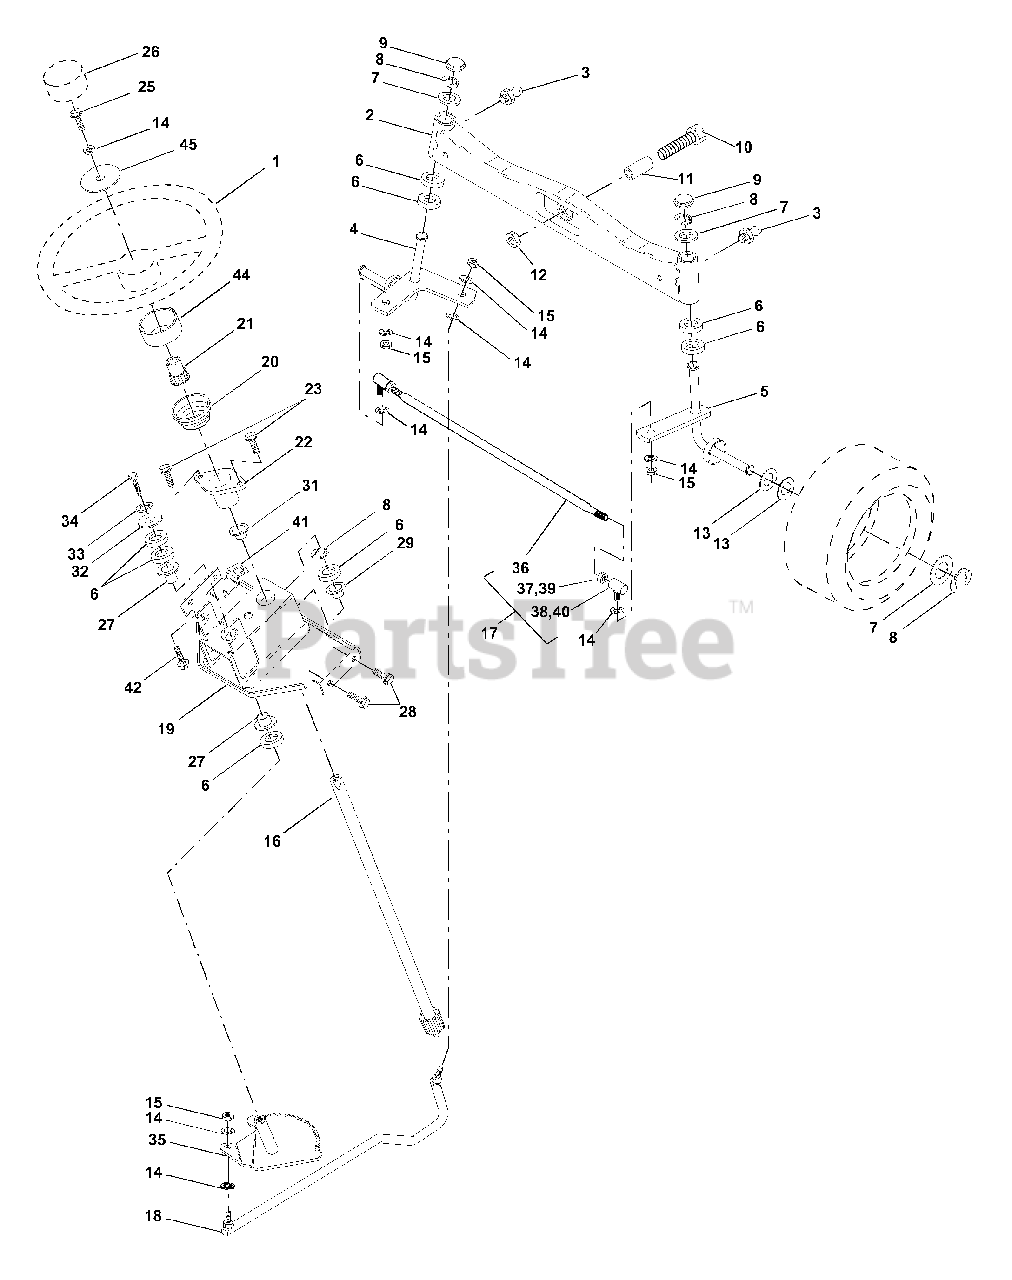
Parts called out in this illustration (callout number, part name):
1	Wheel, Steering
2	Axle, Front
3	Fitting, Grease
4	Spindle Asm, LH
5	Spindle Asm., RH
6	Bearing, Race Thrust Harden
7	Washer 25/32 x 1-5/8 x 16 Ga.
8	Ring, Klip #T5304-75
9	Cap, Spindle
10	Bolt, Fin Hex 5/8-11 x 2-3/4
11	Spacer Brg Axle Front 1.570
12	Nut, Lock Flange 5/8-11 Unc
13	Washer 25/32 x 1-1/4 x 16 Ga.
14	Washer, Lock Hvy Hlcl Spr 3/8
15	Nut Lock Center 3/8-24 Unf
16	Shaft Asm., Steering
17	Rod Asm., Tie Ball J Ball Vgt
18	Draglink, Ball Joint Solid Vgt
19	Support Asm., Steering Vgt
20	Boot Steering
21	Adapter, Wheel Steering
22	Bushing, Strg.
25	Bolt, Fin Hex 3/8-16 x 1 Gr. 5
26	Cap , Wheel Steering
27	Bearing, Col. Strg.
28	Screw 3/8-16 x 3/4
29	Bearing, Flange
31	Bushing, Nyliner Snap
32	Washer 11/32 x 1 x 10 Ga.
33	Washer, Lock Hvy Hlcl Spr 5/16
34	Bolt, Hex Hd 5/16-18 x 3/4
35	Gear, Sector Steering
36	Tie Rod
37	Jam Nut RH Thread
38	Joint Asm. Ball RH Thread
39	Jam Nut LH Thread
40	Joint Asm Ball LH Thread
41	Bracket Switch Inerlock VGT97
42	Screw 5/16-18 x 1/2
44	Extension Steering Premium
45	Washer 13/32 x 1-1/20 x 11 Ga.
